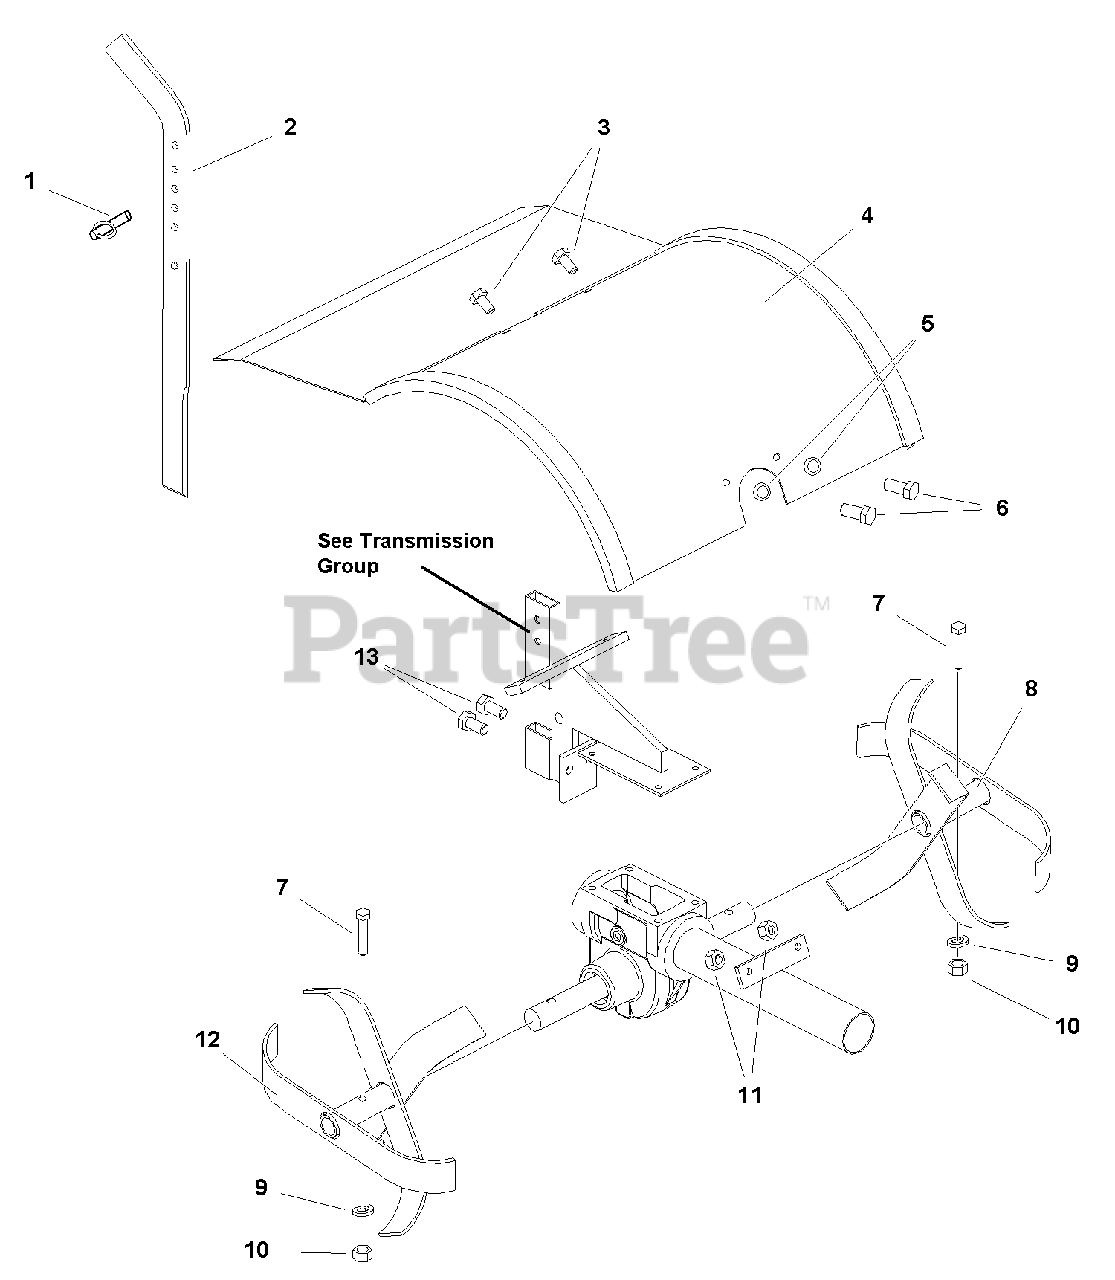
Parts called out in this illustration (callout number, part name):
1	PIN, Detent, 5/16
2	LEVER, Depth Regulator
3	CAPSCREW, Hex Head, 1/4 - 20 x 1/2
4	HOOD, Tiller, No Decal
5	LOCKWASHER, Spring, 5/16
6	CAPSCREW, Hex Head, 5/16-18 x 1/2
7	CAPSCREW, Hex Head, 3/8-16 x 1-3/4
8	TINE ASSEMBLY, LH
9	LOCKWASHER, Spring, 3/8
10	NUT, Hex Center Lock, 3/8-16
11	NUT, Hex Flange, 5/16-18
12	TINE ASSEMBLY, RH
13	BOLT, Hex Flange Head, 5/16-18 x 1/2
